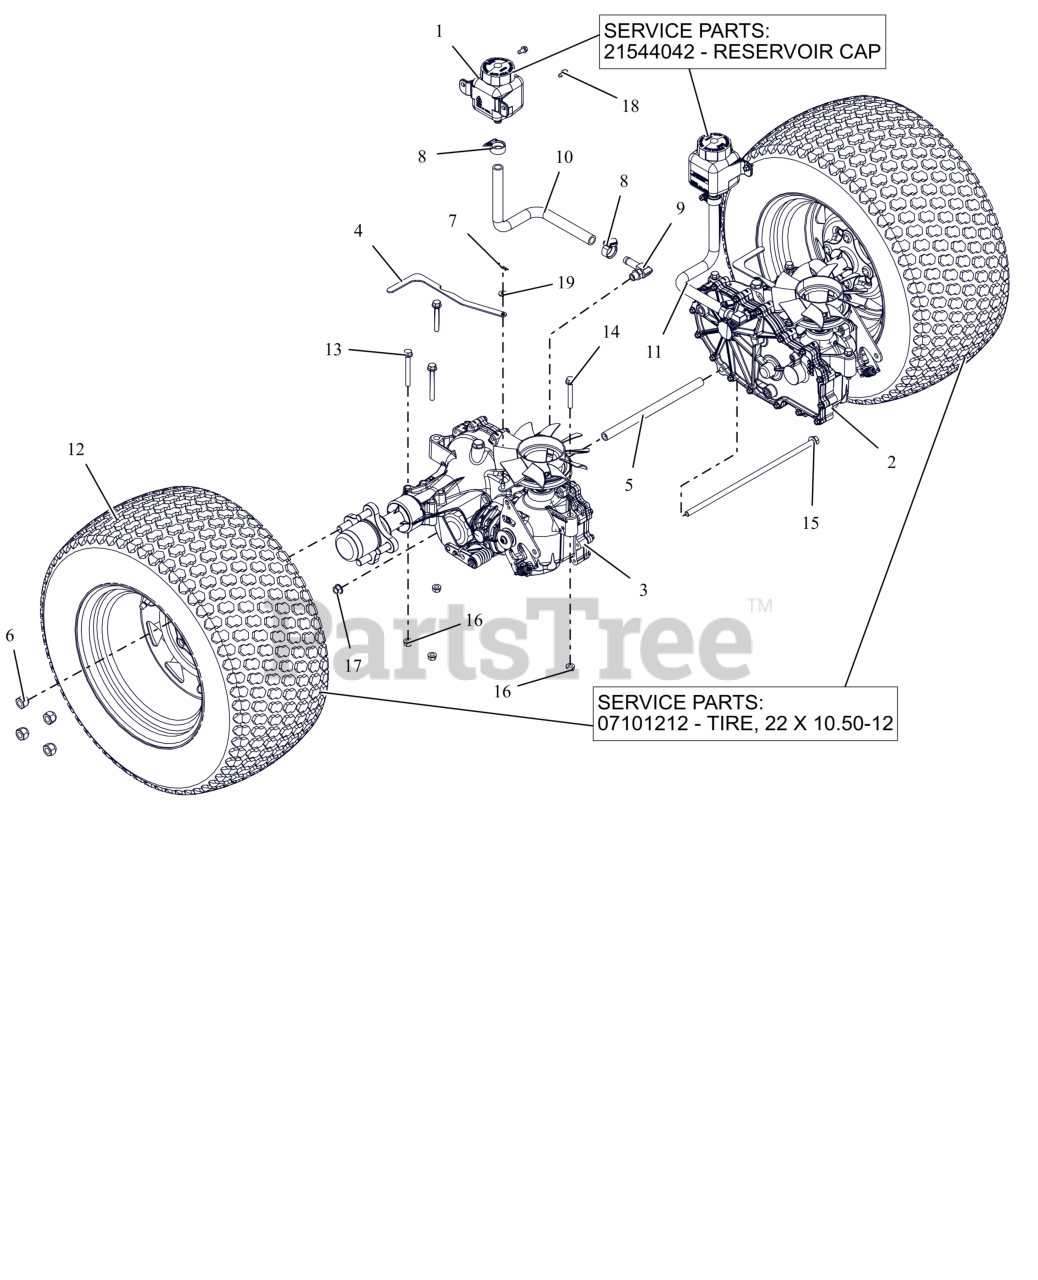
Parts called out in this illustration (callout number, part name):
1	TANK, EXPANSION
1	CAP, HYDRO RESERVOIR REPLAC.
2	TRANSAXLE, ZT3100 LH
3	TRANSAXLE, ZT3100 RH
4	BRKT, VALVE DUMP
5	SPCR,TRANS. .406IDX.63ODX9.95L
6	NUT, WHEEL .50-20 ZCC
7	PIN, HAIR #225 .072X1.09
8	CLAMP,.88 DIA. HOSE
9	FITTING, HYD (90 DEG)
10	HOSE, FORMED EXPANSION -HD RH
11	HOSE, FORMED EXPANSION -HD LH
12	ASM, WHL/TIRE 22X10.50-12 K500
12	TIRE, 22X10.50-12
13	BLT,HEX-FLG .31-18X2.75 G5 ZCC
14	BLT,HEX-FLG .31-18X2.25 G5 ZCC
15	BLT,HEX-FLG .38-16X13 G5 ZCC
16	NUT,LK-CTR-FLG .31-18 GF ZCC
17	NUT-LK-CTR-FLG .375-16 GF ZCC
18	SCR-TAP .25-20X.50 HWH ZCC
19	WSHR,FLT .281X.625X.065 ZCC
